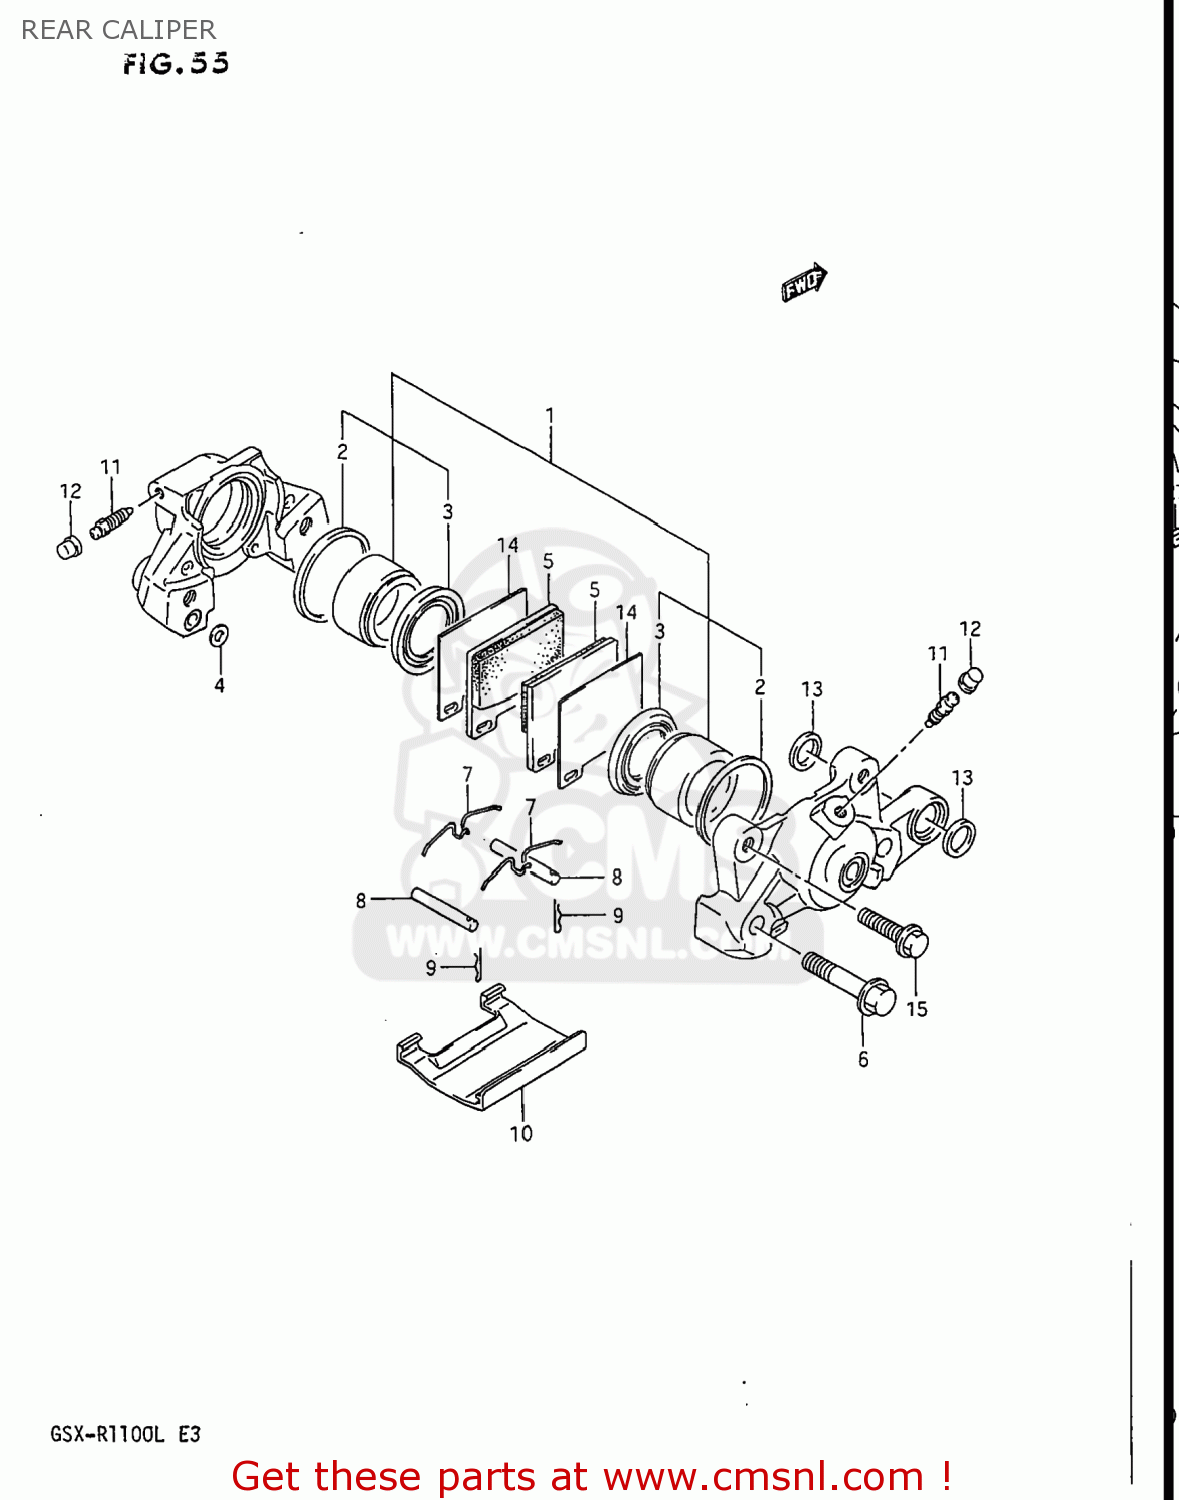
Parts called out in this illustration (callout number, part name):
1	PISTON SET
2	SEAL,PISTON
3	BOOT
4	SEAL,JOINT
5	PAD,BRAKE
6	BOLT
7	SPRING
8	PIN,PAD
9	CLIP,PAD PIN
10	COVER
11	BLEEDER
12	CAP,BREATHER
13	SEAL,RR CUSHION ROD LWR
14	SHIM,PAD
15	BOLT
